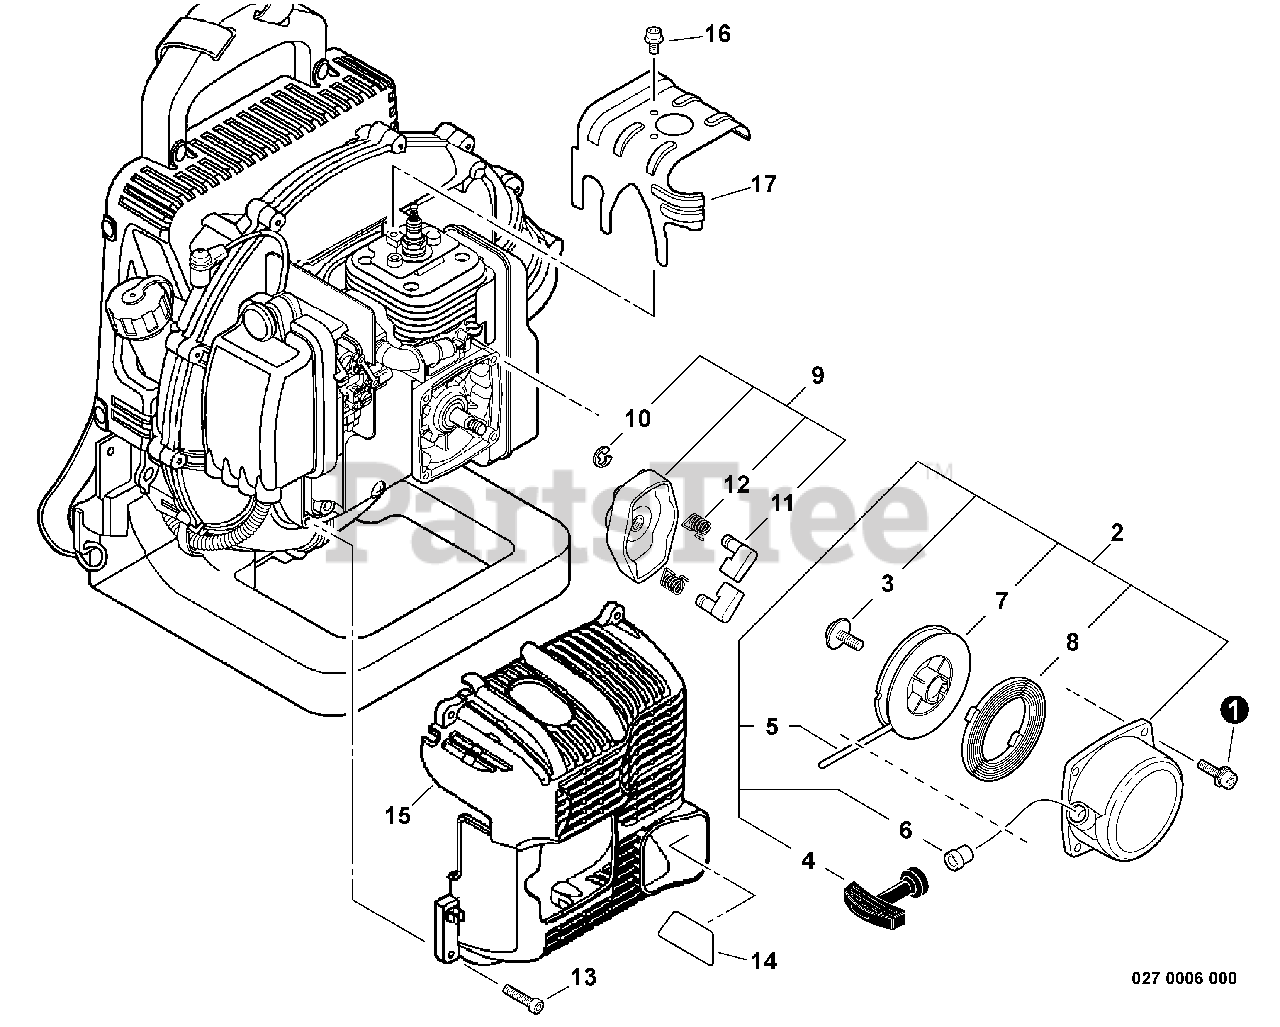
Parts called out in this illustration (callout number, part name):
1	SCREW - 5X18
2	STARTER ASSY
4	GRIP, STARTER
5	ROPE, STARTER
6	GUIDE, ROPE
7	REEL, ROPE
8	SPRING, REWIND
9	STARTER PAWL ASSY
10	RING, RETAINING - 4
11	PAWL, STARTER
12	SPRING, RETURN
13	SCREW - 5X20 -- TAPPING
14	DEFLECTOR, HEAT
15	COVER, ENGINE
16	SCREW - 5X8
17	SHIELD, CYLINDER
